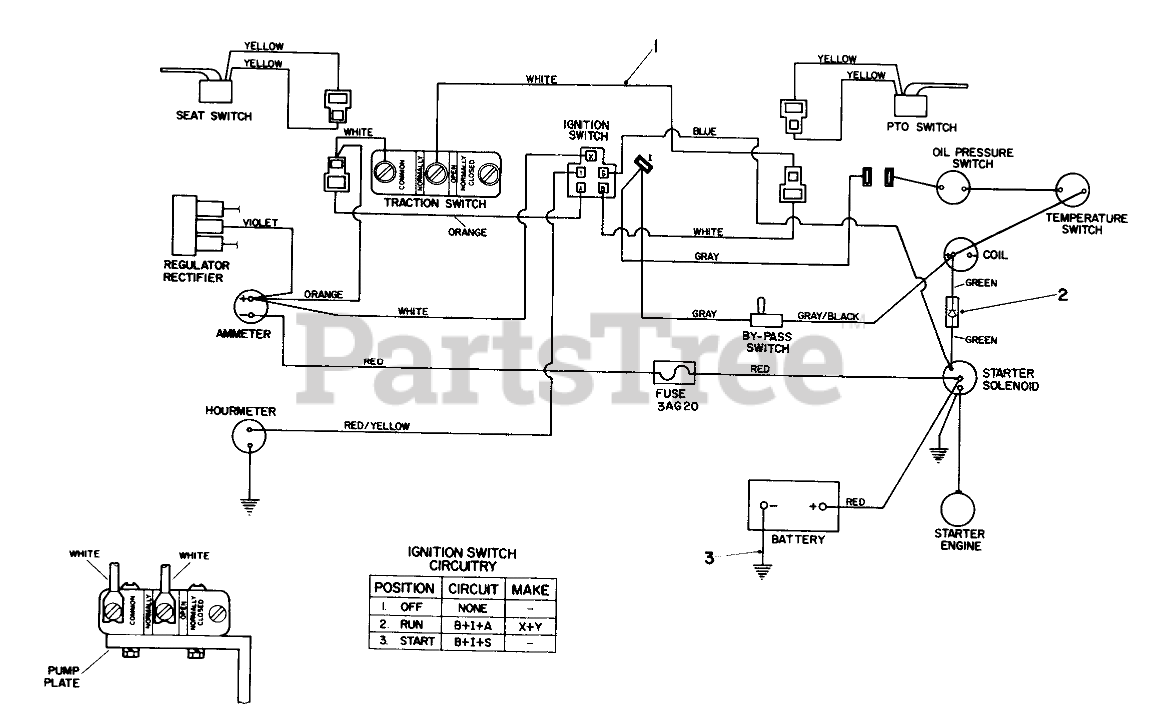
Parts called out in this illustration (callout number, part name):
1	Wire Harness (Incl. Ref. #2)
2	JUMPER WIRE ASM
3	BATTERY GROUND WIRE
